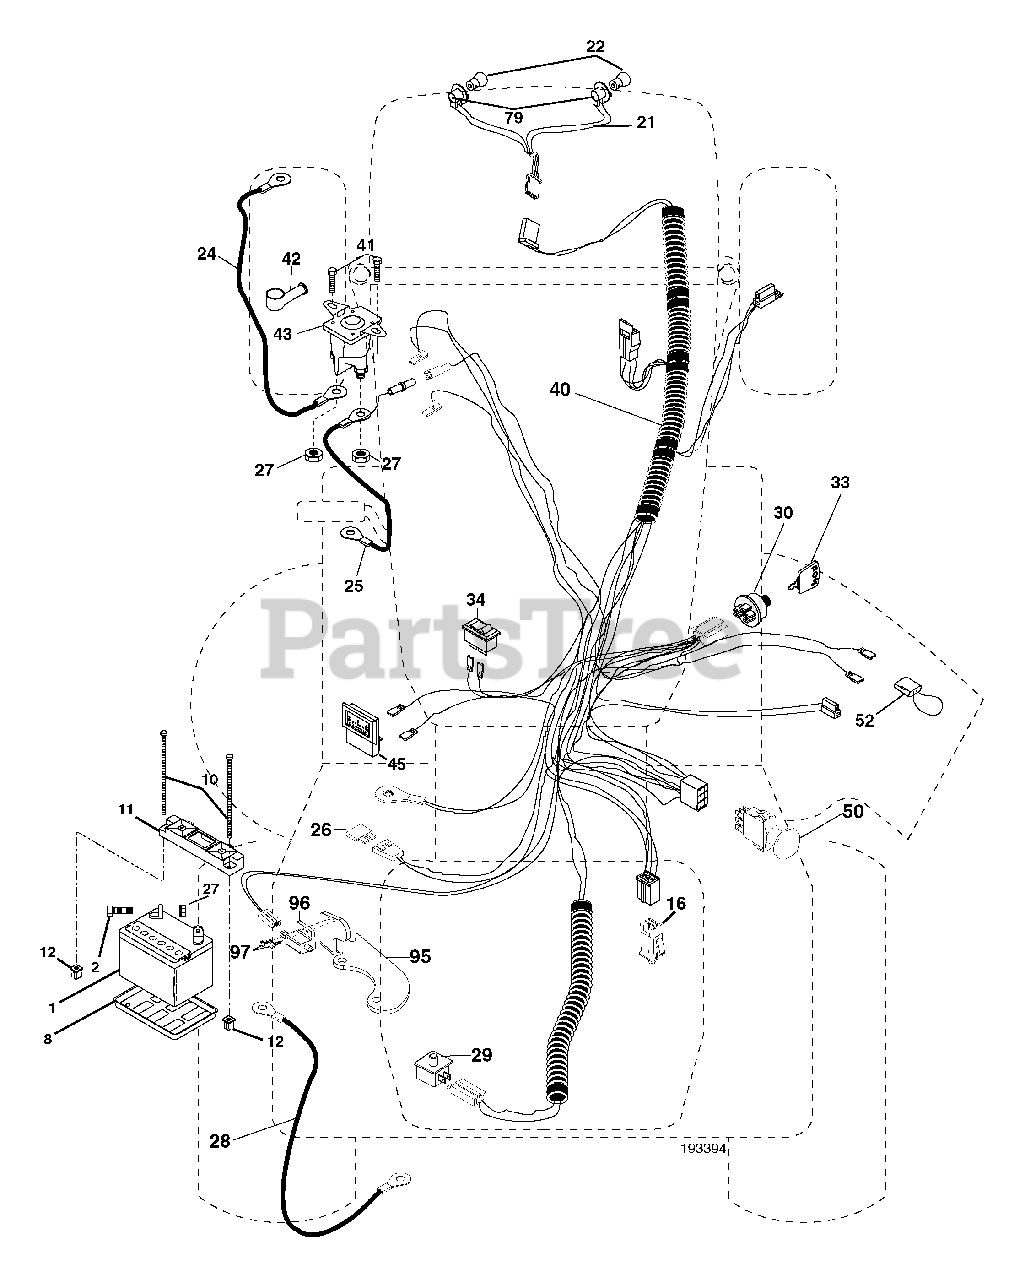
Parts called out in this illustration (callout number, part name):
1	Battery
2	Bolt Hex Head 1/4-20 x 3/4
8	Tray, Battery
10	Bolt, Battery Front 1/4-20 x 7.5 Zinc
11	Holddown Battery Front Mount
12	Nut, Push Nylon 1.4" Battery Front
16	Switch Interlock
21	Harness Socket Light w/4152J
22	Bulb Light
24	Cable Starter
25	Cable, Battery
27	Nut Keps Hex 1/4-20
28	Cable, Ground
29	Switch, Plunger
30	Switch, Ign
34	Switch Light/Reset
40	Harness Ign.
41	Screw Thd Cut 1/4-20 x 1/2
42	Cover, Terminal Red
43	Solenoid
50	Switch, PTO
52	Protection Wire Loop
79	Bulbholder Asm
95	Bracket ROS
96	Switch Intek
